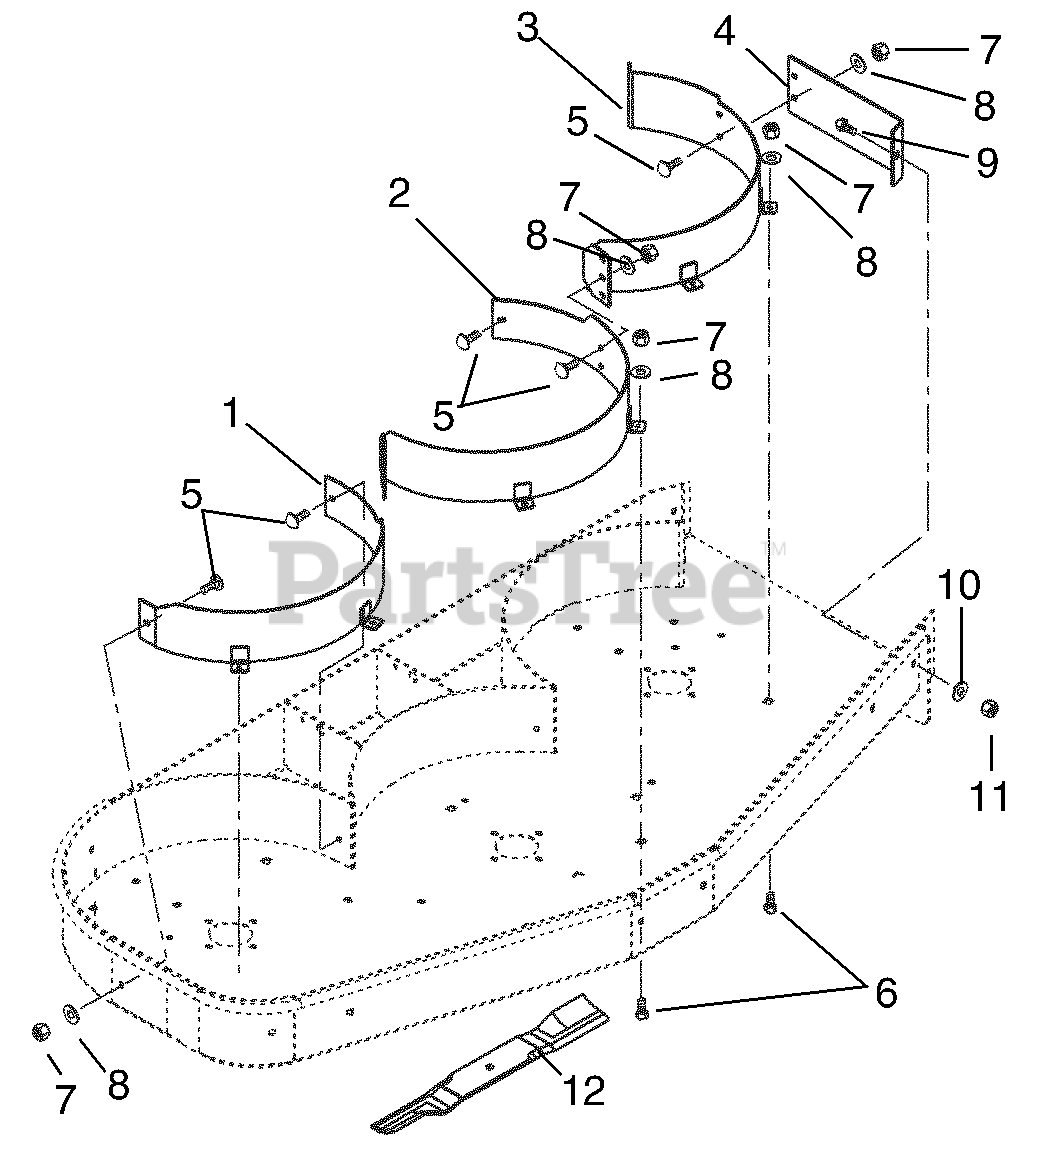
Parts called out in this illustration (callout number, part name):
1	BAFFLE-MULCH-LEFT FRONT-50"
1	BAFFLE-MULCH-LEFT FRONT-60"
1	BAFFLE-MULCH-LEFT FRONT-72"
2	BAFFLE-MULCH-CENTER FRONT-50"
2	BAFFLE-MULCH-CENTER FRONT-60"
2	BAFFLE-MULCH-CENTER FRONT-72"
3	BAFFLE-MULCH-RIGHT FRONT-50"
3	BAFFLE-MULCH-RIGHT FRONT-60"
3	BAFFLE-MULCH-RIGHT FRONT-72"
4	BAFFLE - END MULCH - 50
4	BAFFLE, END MULCHING (60")
4	SUPPORT, MULCH BAFFLE
5	@BLT-RDHDSQNK .31-18X.75 G5YZ
6	@BLT-HEX .31-18X1.00 GR5 YWZC
7	@NUT-LK-NYL .312-18 YWZC
8	@WSHR-FL-STL.344X.688X.065YWZC
9	@BLT-HEX .38-16X1.00 GR5 YWZC
10	@WSHR-FL-STL.38X.875X.083 YWZC
11	@NUT-LK-NYL .38-16 YWZC
12	BLADE, MOWER 50" TUNG MULCH
12	BLADE, TUNG MULCH MOWER 60"
12	BLADE, 72" TUNGSTEN MULCH
